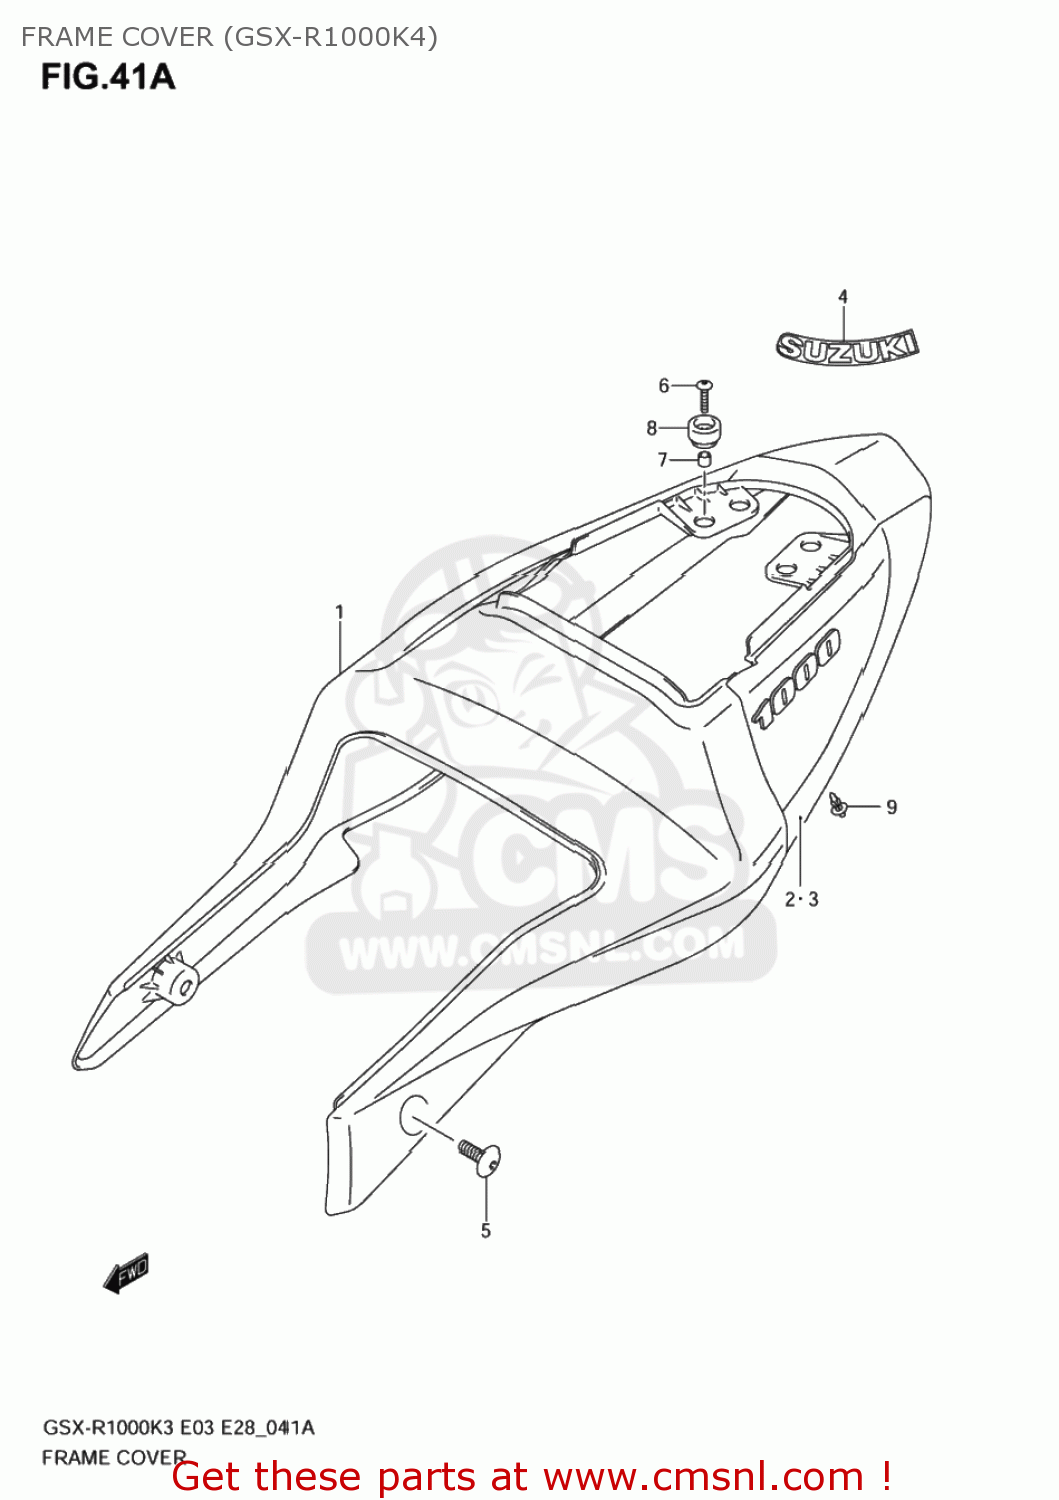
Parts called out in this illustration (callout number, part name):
1	COVER ASSY,FRAME(WHITE)
2	TAPE,FRAME COVER,R
3	TAPE,FRAME COVER,L
4	EMBLEM,SUZUKI
5	SCREW(6X16)
6	SCREW(6X25)
7	SPACER(6.5X10X9.4)
8	CUSHION
9	CLIP(BLACK)
